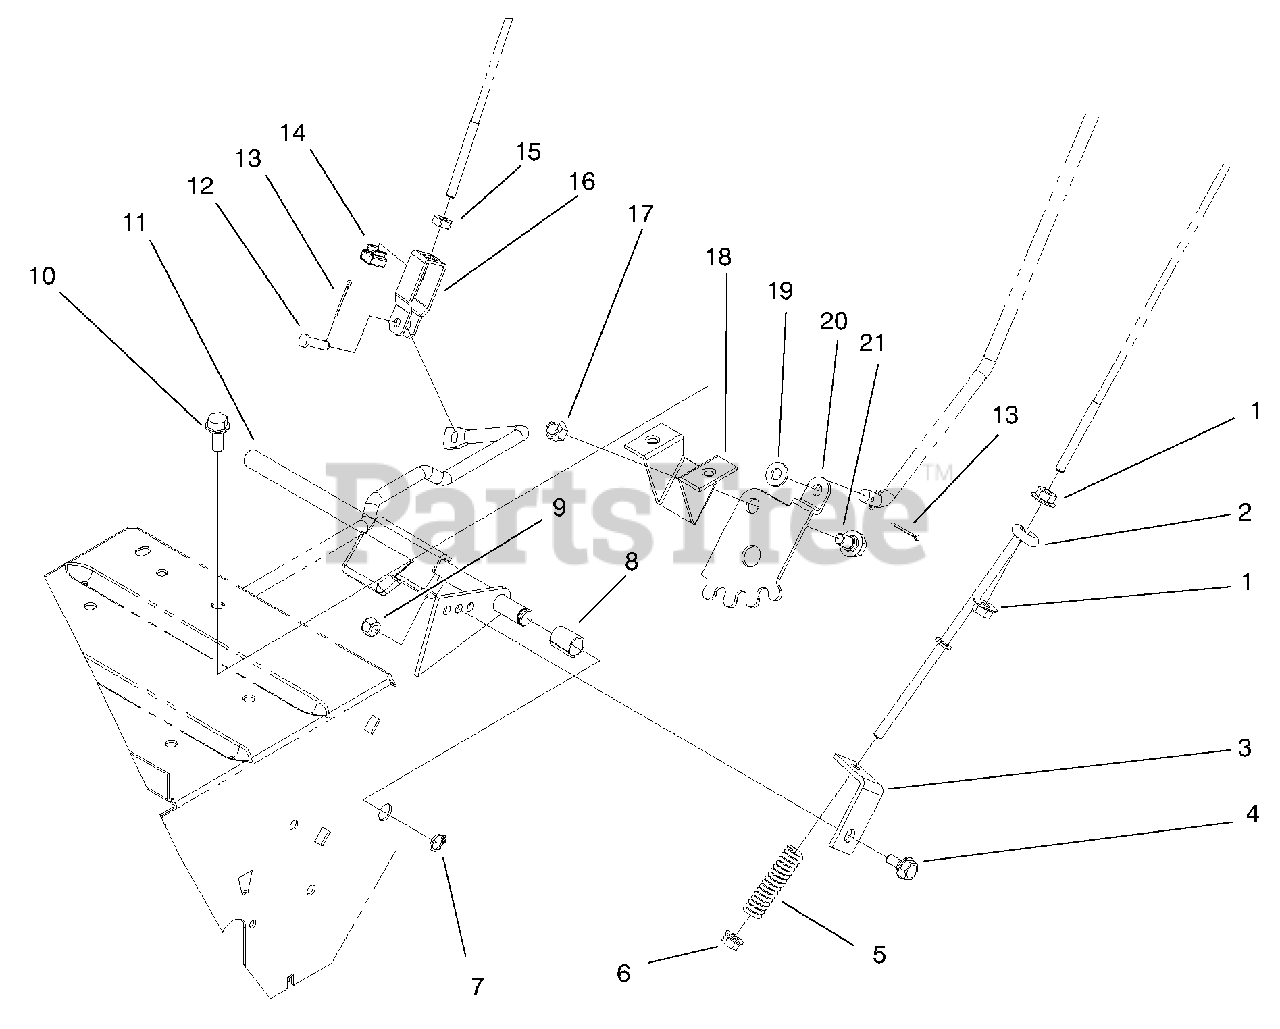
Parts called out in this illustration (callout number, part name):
2	Rod-Traction, Lower
3	Bracket-Traction
6	Nut-Hex, Flange
7	Ring-Retaining
9	Nut-Lock
11	Traction Arm Assembly
12	Pin-Clevis
13	Pin-Cotter
14	Nut-Retained
15	Nut-Jam
17	Nut-Lock
18	Mount-Lever
19	Washer-Flat
20	Gear-Quadrant
21	Bolt-shoulder
